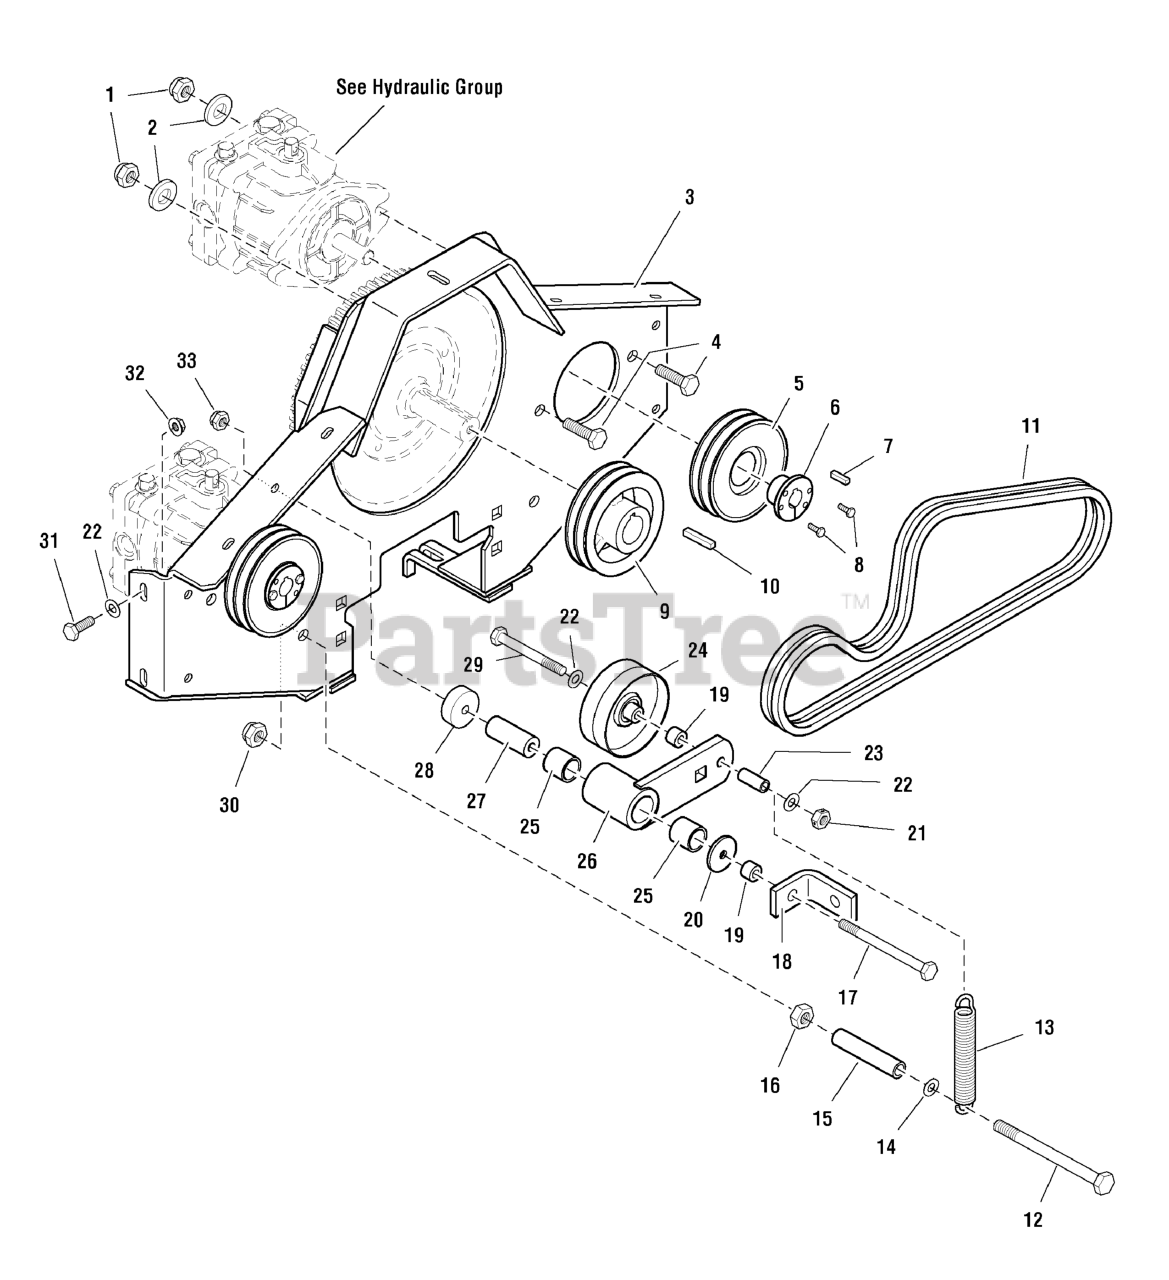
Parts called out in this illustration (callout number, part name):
1	NUT, Hex, Nylon Lock, 1/2-20
2	WASHER, Frame Retaining
3	PUMP MOUNT PLATE
4	BOLT, 1/2-20 X 1-3/4" GD8 CZ
5	PULLEY, Pump Drive
6	HUB, Taper Lock
7	KEY, 5MM SQ. x 25MM w/ Round Ends
8	BOLT, 1/4-20 X 1" GD5 CZ
9	PULLEY, 5.75" OD X 1.375" BORE, DOUBLE A
10	KEY, 5/16" SQ RD ENDS, 1.46 LG
11	BELT, Pump Drive (set of 2)
12	BOLT, 1/2-13 x 5
13	SPRING, Extension, Swivel End
14	WASHER, 1/2 SAE
15	HOSE, 3-1/4
16	NUT, 1/2-13 Hex Jam
17	BOLT, 3/8-16 X 4-1/2" GD5 CZ
18	SPRING ANCHOR
19	SPACER, .39 x .75 x .38
20	WASHER, 3/8 x 1-3/4
21	NUT, 3/8-16 Hex Side Lock
22	WASHER, 3/8 SAE
23	SPACER, .38 x .50 x .75
24	PULLEY, Idler, Flat
25	BUSHING, Brass
26	PUMP DRIVE IDLER ARM
27	SPACER, .39 X 1.00 X 2.55, SS
28	SPACER, .45 x 1.88 x .38
29	BOLT, 3/8-16 X 3" GD5 CZ
30	NUT, 1/2-13 HEX NYLON LOCK
31	BOLT, 3/8-16 X 1" GD5 CZ
32	NUT, 3/8-16 Hex Serrated Flange
33	NUT, 3/8-16 HEX NYLON LOCK
